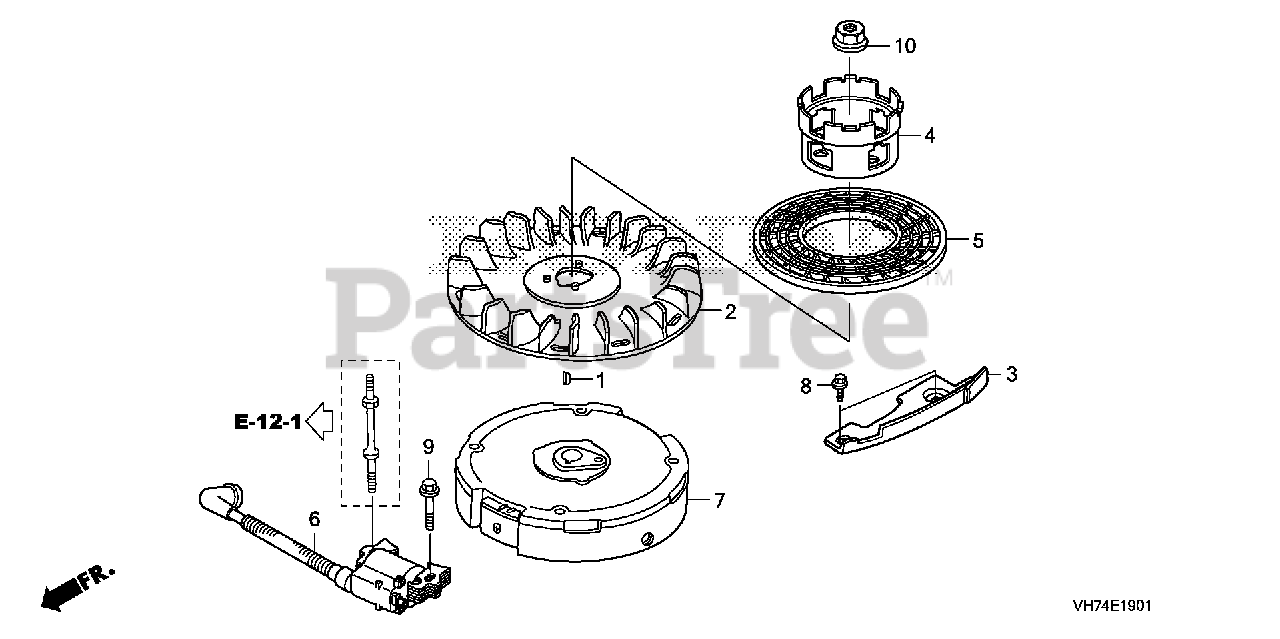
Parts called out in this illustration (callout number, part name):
1	KEY, SPECIAL WOODRUFF (25X18)
2	FAN, COOLING
3	PLATE, SIDE
4	PULLEY, STARTER
5	GRID, SCREEN
6	COIL ASSY., IGNITION (TOYO)
6	COIL ASSY., IGNITION (PHELON)
7	FLYWHEEL
8	BOLT, FLANGE (6X12) (CT200)
9	BOLT, FLANGE (6X23) (CT200)
10	NUT, SPECIAL (14MM)
